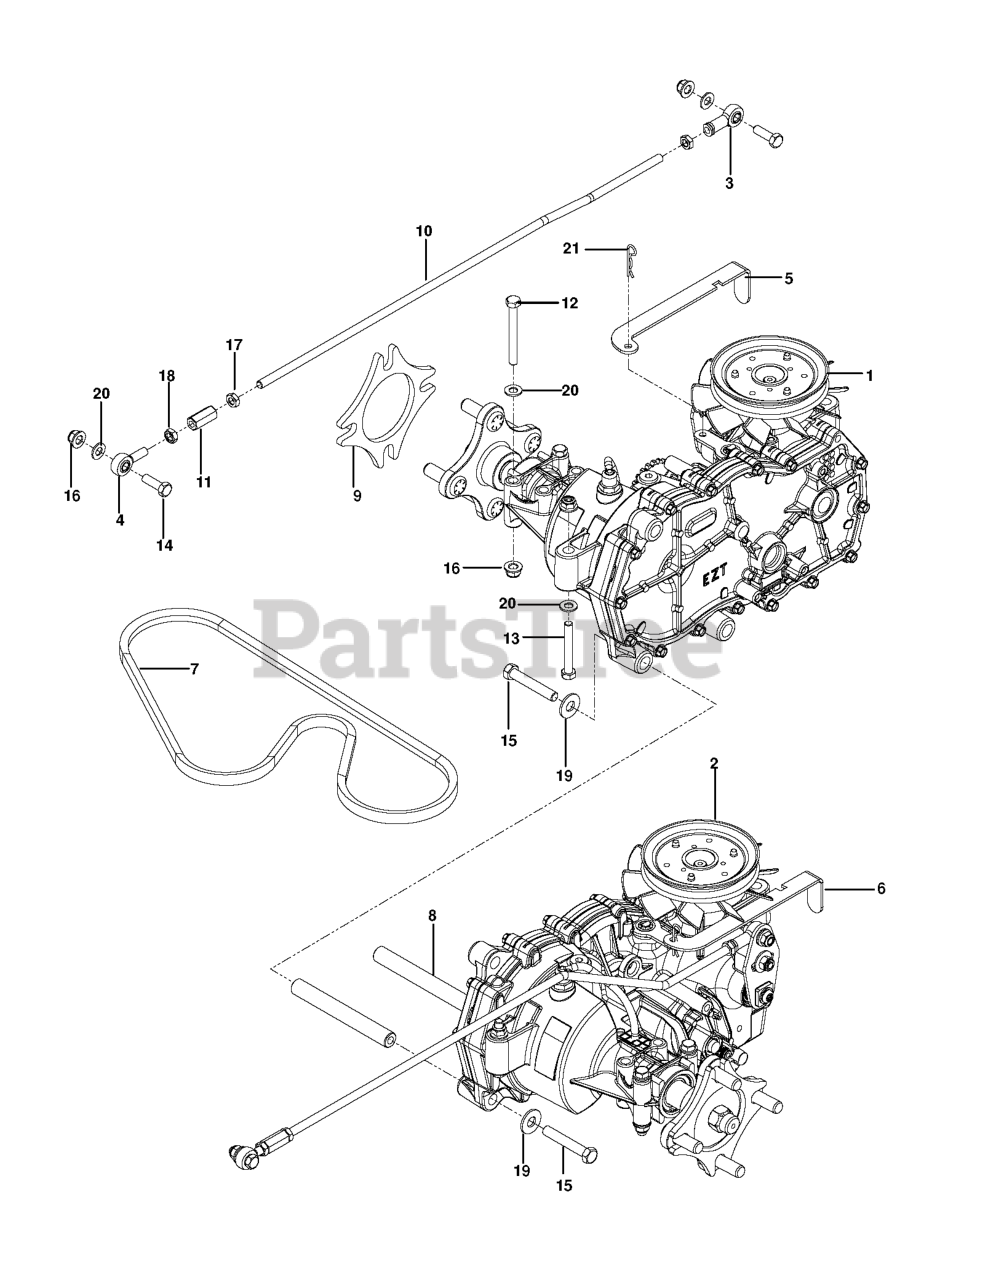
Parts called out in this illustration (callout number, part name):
1	HG_HYDRO RH
2	HG_HYDRO LH
3	RH ROD END
4	ROD END LH
5	RELEASE LEVER RH
6	RELEASE LEVER LH
7	BELT, EL 51.O4
8	SPACER, HYDRO
9	SPACER, WHEEL
10	CONTROL ROD
11	ROD END COUPLER
12	HCS 5/16C X 2-3/4
13	CAPSCREW
14	HCS 5/16C X 1
15	HCS 3/8C X 2 1/4
16	5/16-18 NYLOC FLANGE NUT
17	NUT 5/16-24 UNF HEX JAM
18	NUT 5/16F LEFTHAND
19	WASHER 3/8 FLAT
20	FLAT WASHER 5/16 SAE
21	HAIRPIN #2
